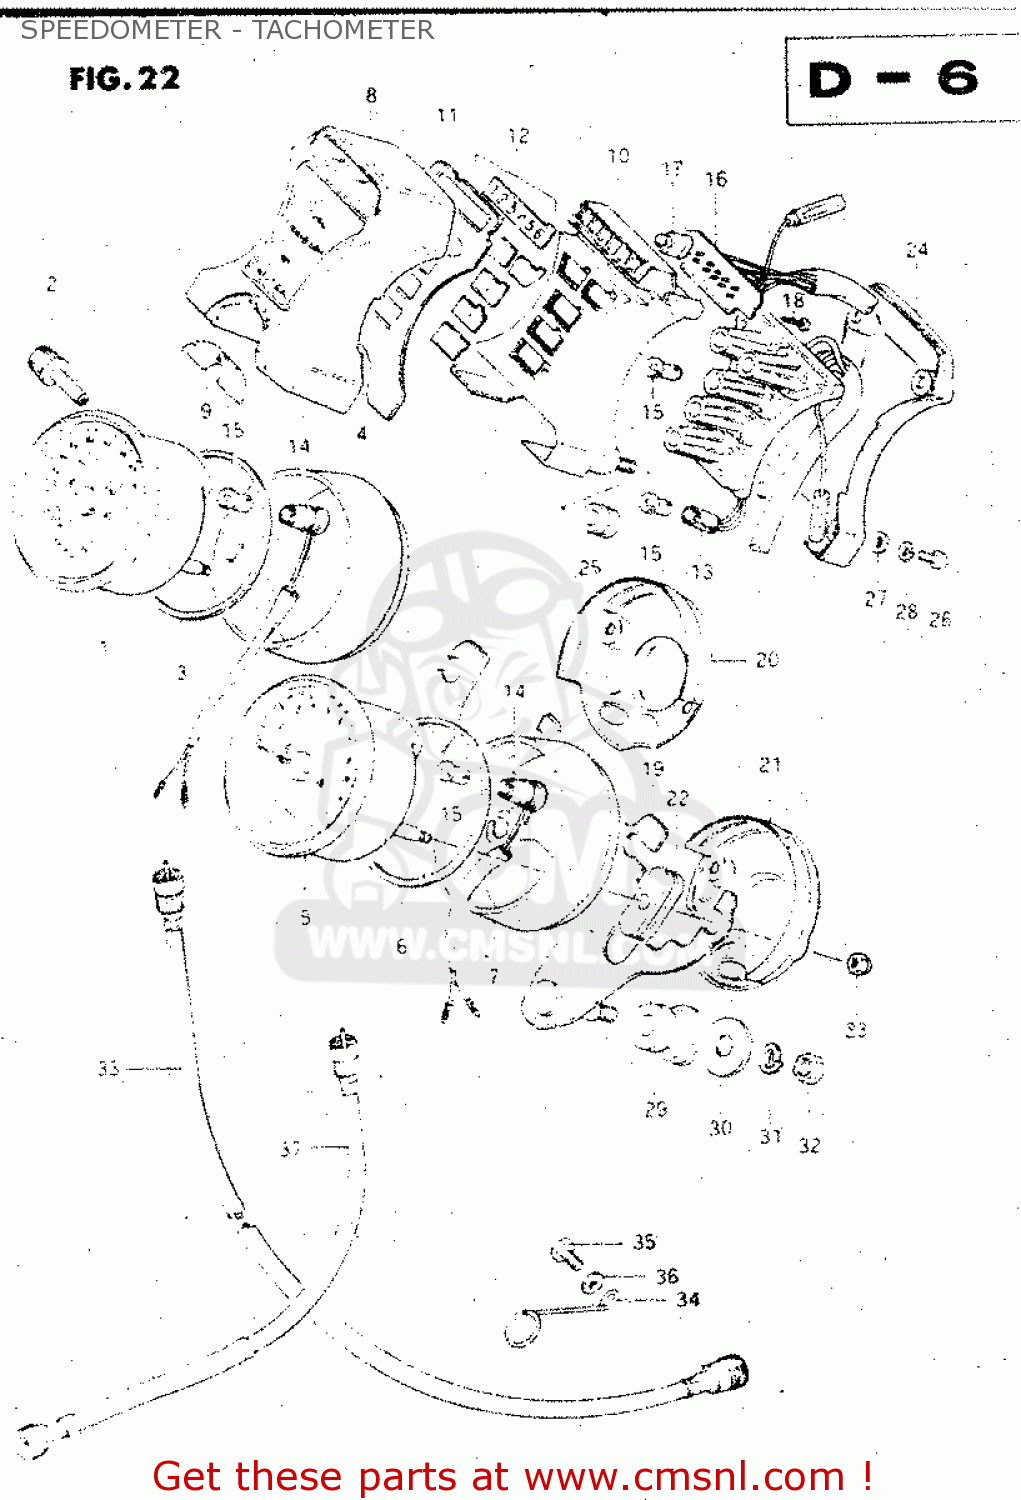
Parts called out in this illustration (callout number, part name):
1	SPEFDOMETER
2	KNOB,TRIP METER
3	CUSHION,SPEEDOMETER
4	COVER,SPEEDOMETER
5	TACHOMETER
6	CUSHION,SPEEDOMETER
7	COVER,TACHOMETER
8	CASE,PILOT BULB
9	PAD
10	CASE,PILOT BULB,INNER
11	PLATE,PILOT BOX
12	LENS SET,PILOT LAMP
13	SOCKET
14	SOCKET,METER
15	BULB(12V3.4W,STANLEY,A72A)
16	SOCKET,GEAR INDICATOR
17	BULB(14V1.12W)
18	SCREW,GEAR INDICATOR
19	BRACKET,COMBINATION METER
20	COVER,SPEEDOMETER,UNDER
21	COVER,TACHOMETER,UNDER
22	CUSHION,METER
23	NUT
24	COVER,PILOT BOX,UNDER
25	CUSHION
26	SCREW
27	WASHER
28	LOCK WASHER
29	CUSHION,METER BRACKET
30	WASHER (8.5X29X1.6)
31	LOCK WASHER
32	NUT
33	CABLE ASSEMBLY,SPEEDOMETER
34	CLAMP,SPEEDOMETER CABLE
35	BOLT, UPPER
36	WASHER
37	CABLE ASSEMBLY,TACHOMETER
